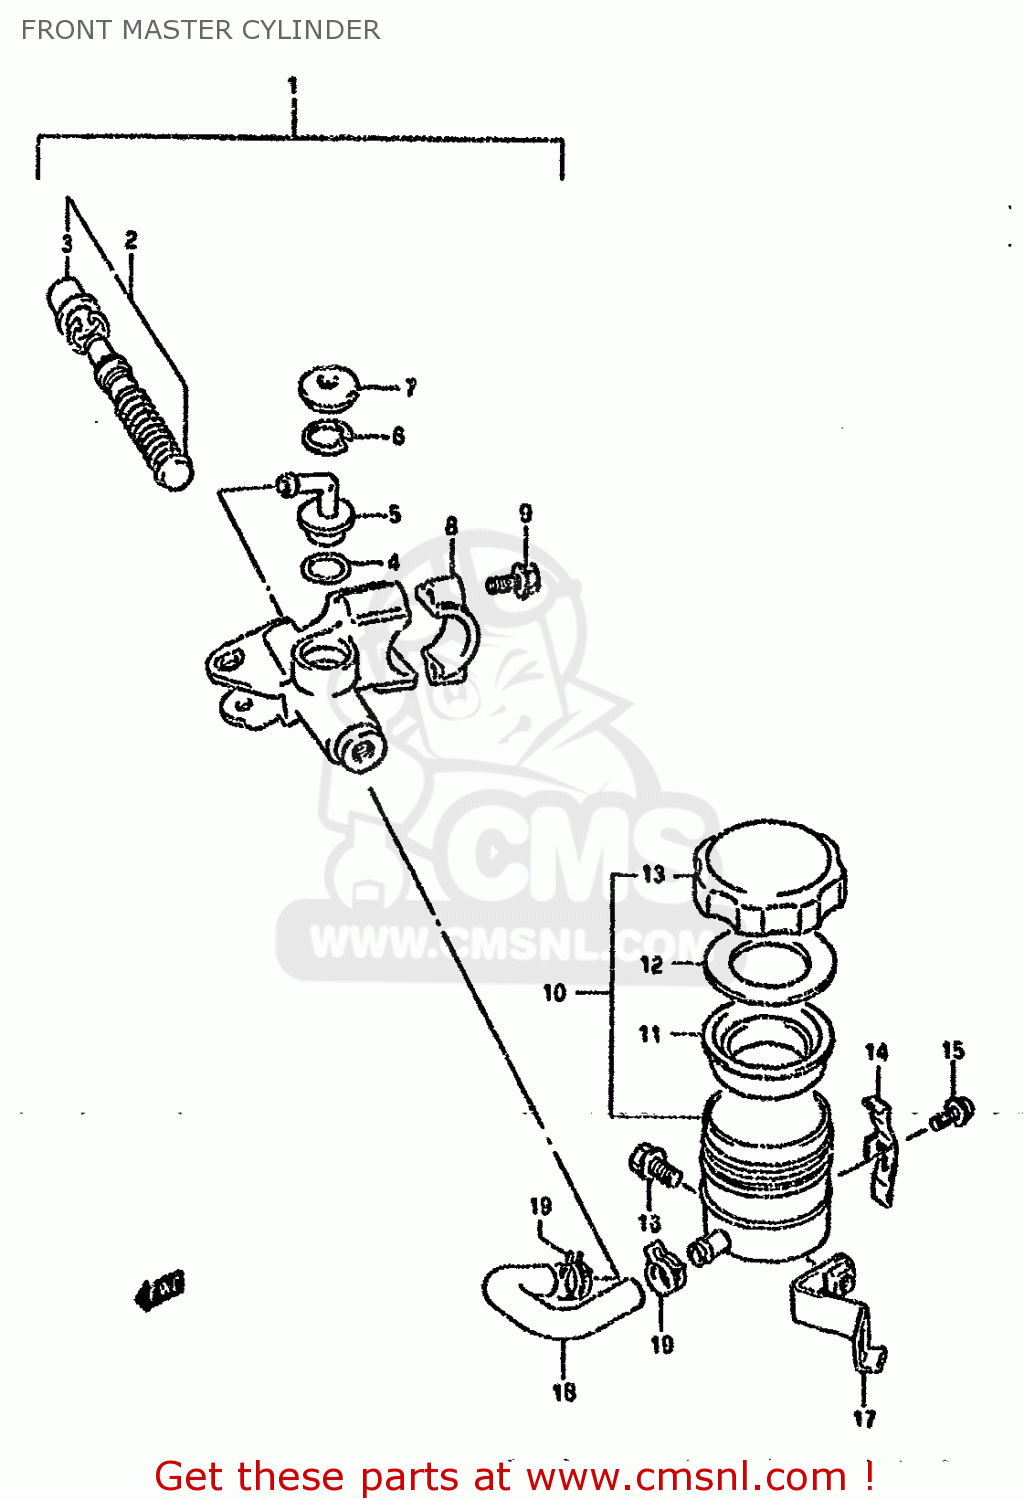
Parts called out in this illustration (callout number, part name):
1	CYLINDER ASSY,FR MASTER
2	PISTON & CUP SET
3	BOOT
4	O RING
5	CONNECTOR
6	CIRCLIP
7	COVER,DUST
8	HOLDER
9	BOLT
10	TANK ASSY,RESERVOIR
11	DIAPHRAGM
12	PLATE,DIAPHRAGM
13	CAP
14	PLATE,RESERVOIR TANK CAP
15	SCREW
16	BOLT
17	BRACKET,RESERVOIR TANK
18	HOSE,RESERVOIR TANK FR
19	CLAMP,RESERVOIR TANK FR
